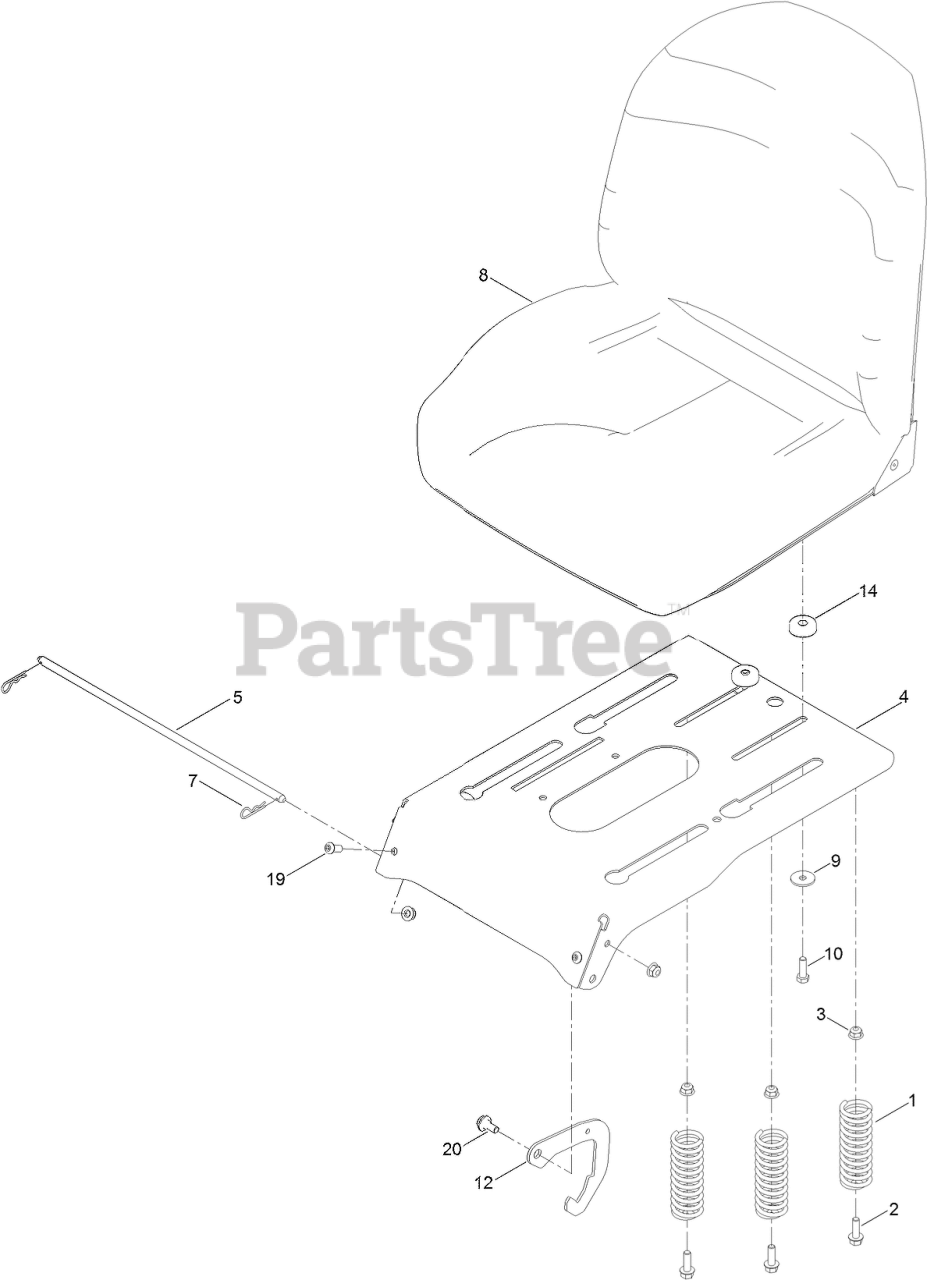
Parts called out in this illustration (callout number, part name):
1	SPRING-COMPRESSION
2	SCREW-HHF
3	NUT-HF, NI
4	PAN-SEAT, DELUXE
5	ROD-PIVOT, NARROW
7	PIN-COTTER
9	WASHER-PIVOT
10	SCREW-HH
12	LATCH-SEAT
14	BUSHING-SLIDE, SEAT
19	SCREW-HSBH
20	SCREW-SHOULDER
